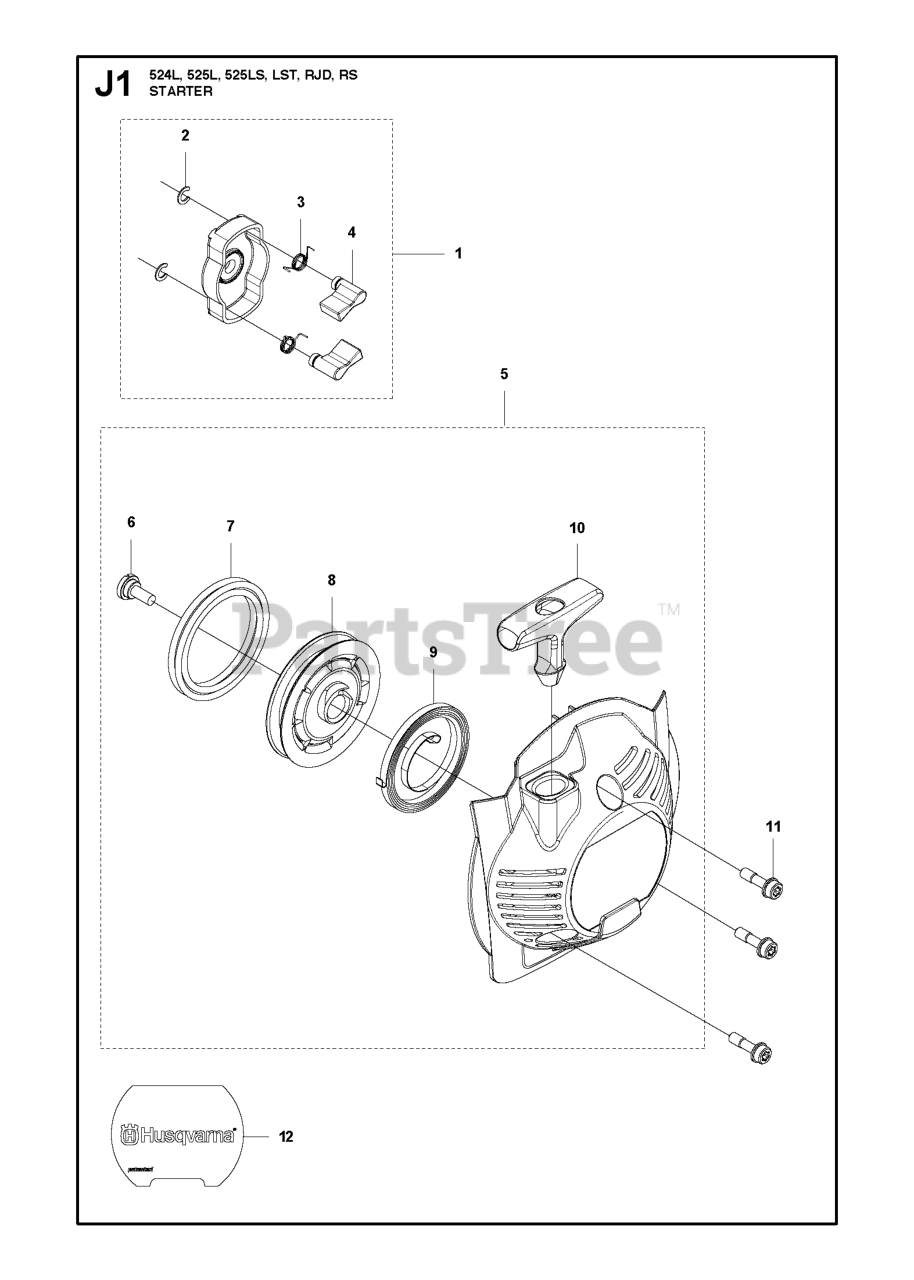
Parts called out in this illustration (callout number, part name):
1	STARTER PULLEY ASSY
2	E-RING
3	SPRING
4	RATCHET
5	STARTER ASSY
6	SCREW
7	ROPE
8	STARTER PULLEY
9	SPRING, SPIRAL
10	STARTER HANDLE
11	BOLT
12	DECAL STARTER
